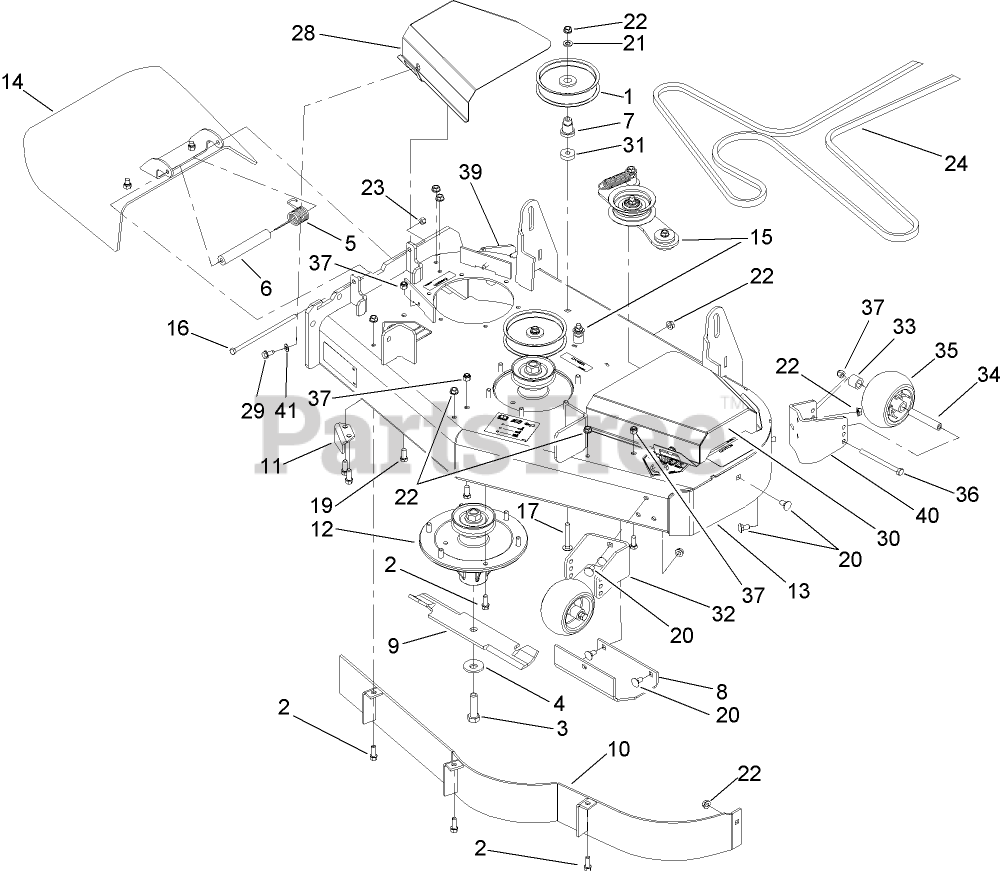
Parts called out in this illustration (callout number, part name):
1	PULLEY-IDLER
2	SCREW-HWH
3	SCREW-BLADE
4	Washer-Blade Bolt, Heavy
5	SPRING-TORSION
6	SPACER
7	MOUNT-PULLEY
9	BLADE-14 INCH (HIGH SAIL)
10	BAFFLE ASM
11	BAFFLE-DISCHARGE
12	SPINDLE ASM
13	DECK DECAL ASM
14	DEFLECTOR ASM
15	IDLER ASM
16	SCREW-HH
17	SCREW-CARR
19	SCREW-HH
20	SCREW-CARR
21	WASHER-FLAT
22	NUT-HHF, WHIZ
23	NUT-LOCK, NI
24	BELT-V
28	COVER-RH
29	SCREW-HWHTF
30	COVER-LH
31	Spacer
32	PLATE-SUPPORT, WHEEL
33	TUBE-SPACER
34	TUBE-SPANNER
35	ROLLER-SCALP, ANTI
36	SCREW-HH
37	NUT-LOCK, NI
39	MOUNT-WHEEL, RH
40	MOUNT-WHEEL, LH
41	WASHER-PLAIN
